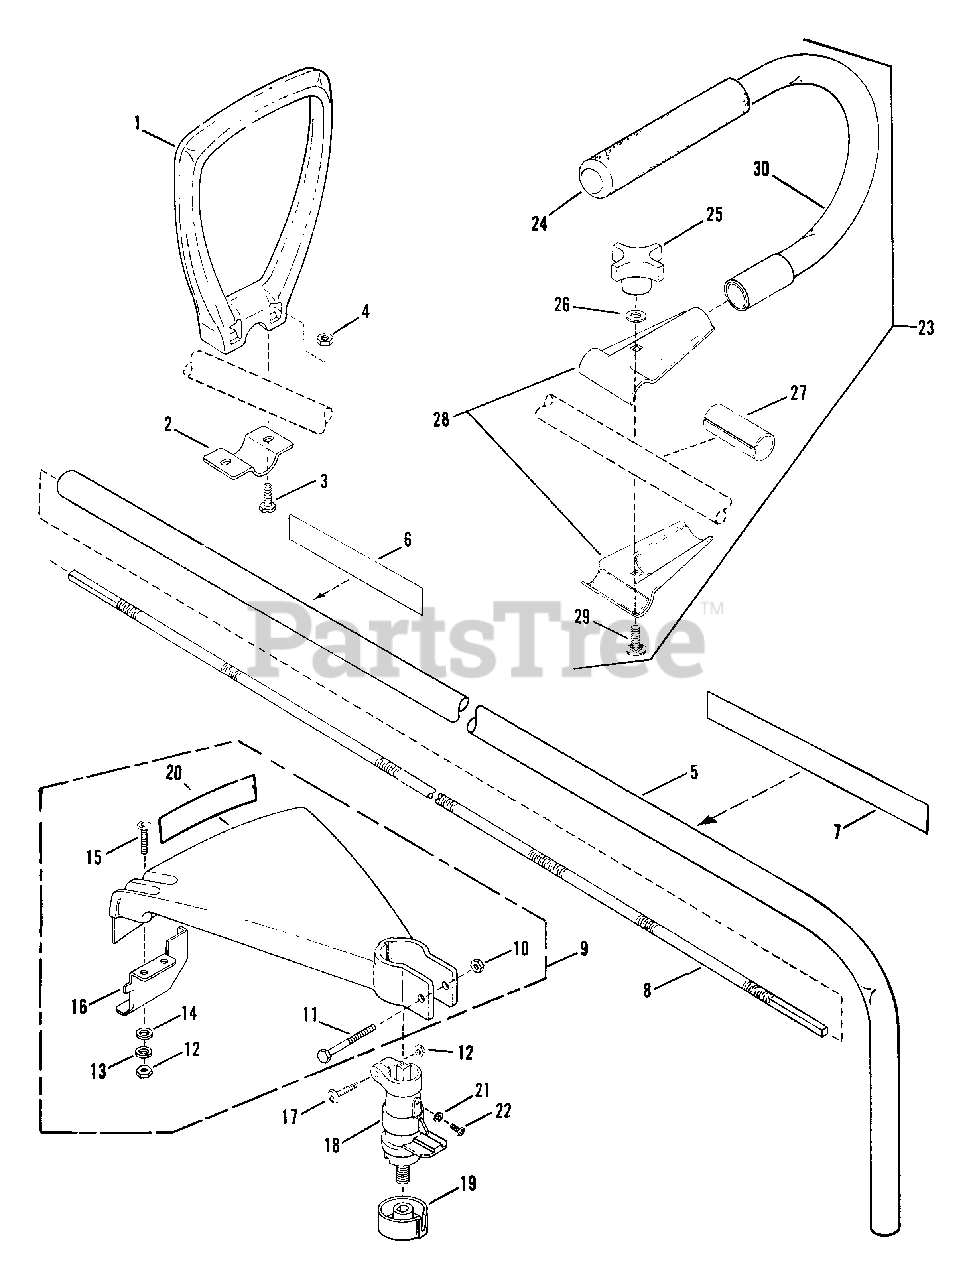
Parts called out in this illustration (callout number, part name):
1	DELTA HANDLE ASSM'Y., Model 212CST & P212CST
2	BRACKET
3	SCREW, M5 x 22mm
4	NUT, M5 Hex
5	TUBE/DECAL ASSM'Y., Model P212CST, 212CST & 213CST
6	LABEL-WARNING
7	LABEL, Model 212CST
8	SHAFT, Flex (53.96" x .245", .2" Square Ends x 1.38")
9	SHIELD ASSM'Y.
10	NUT, #M6 Hex
11	SCREW, M6 x 50mm HH
12	NUT, #10-24 Hex
13	WASHER, Lock
14	WASHER, Flat
15	SCREW, Pan Hd. #10-24 x 3/4"
16	HOUSING - KNIFE
17	SCREW, #10-24 x 1"
18	SPINDLE HOUSING ASSM'Y.
19	COLLAR, Spindle
21	WASHER, Flat
22	SCREW, M4 x 9.5mm Pan Hd.
23	ASSM'Y, "J" HANDLE & Mounting
26	WASHER, 5/16 Flat
27	ISO MOUNT
28	CLAMP ASSM'Y.
29	CARRIAGE BOLT, 5/16-18 x 1-3/4"
30	ASSM'Y "J" Handle
